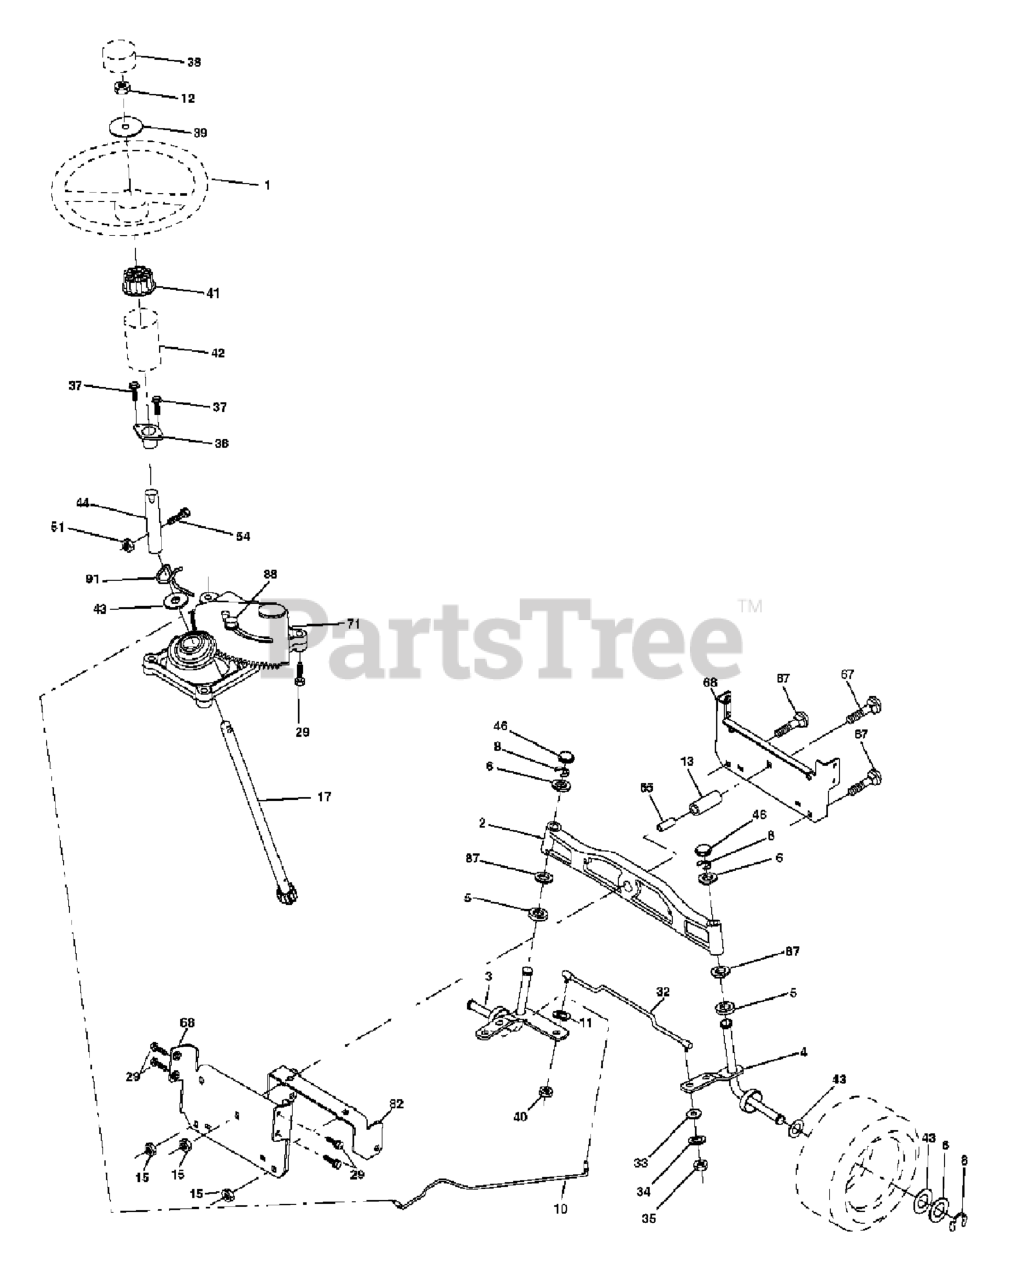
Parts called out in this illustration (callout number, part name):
1	STEERING WHEEL
2	AXLE ASM
3	SPINDLE.ASM.LH.15"TIRES
4	SPINDLE.ASM.RH.15"TIRES
5	THRUST WASHER
10	DRAGLINK.15".TIRES.2001
11	WASHER, LOCK 3/8
12	NUT.HEX.1/2-20
13	TUBE, PIVOT AXLE
15	NUT
17	SHAFT ASM, STEERING
29	SCREW 3/8-16X3/4
32	TIE ROD
33	WASHER M
34	WASHER.LOCK.HVY.HLCL.SPR.5/16
35	NUT, CROWNLOCK
36	BUSHING, STEERING
37	SCREW.TT.#10-32X.5.3/8.FLANGE
38	CAP.WHEEL.STEERING.GREY
39	Washer 9/16 ID x 1-1/2 OD x 11 Ga.
40	GRIPCO NUT
41	STEERING WHEEL ADAPTOR
42	BOOT STEERING
44	EXT, STEERING SHAFT
46	CAP.SPINDLE.BLACK
51	NUT.CROWNLOCK.1/4-28
54	Bolt Hex 1/4-28 UNF x 1-1/4 Gr. 8
65	SPACER BRACE AXLE
67	BOLT
68	BRACE.AXLE.15"TIRES
71	STEERING ASM
82	BRACKET
87	WASHER, FLAT .781 X 1 1/2"
88	BOLT, SHOULDER 7/16-20
91	CLIP.STEERING
